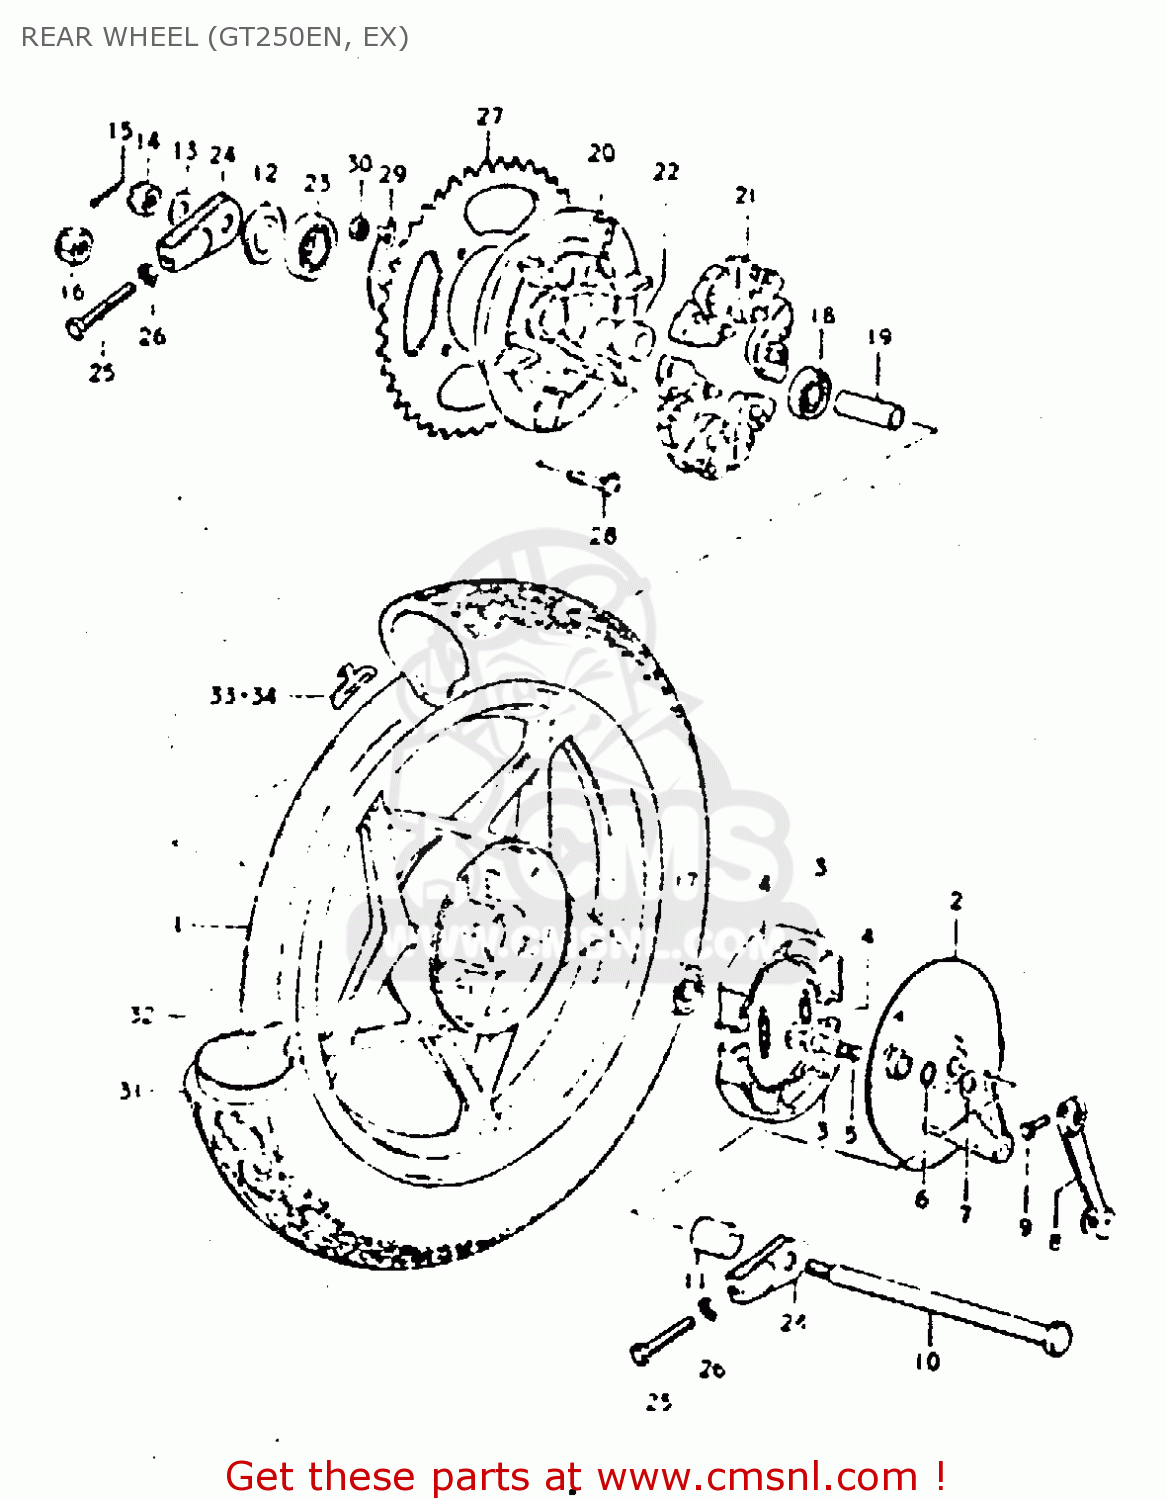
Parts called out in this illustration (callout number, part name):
1	WHEEL, REAR
2	PANEL,REAR HUB
3	SHOE,BRAKE
4	SPRING,BRAKE SHOE
5	CAM,FRONT BRAKE
6	O-RING,BOSS
7	WASHER (15X24X1.6)
8	LEVER,RR BRAKE CAM
9	BOLT
10	AXLE, REAR
11	SPACER
12	SPACER, LH
13	WASHER
14	NUT
15	COTTER PIN
17	BEARING, RH
18	BEARING
19	SPACER(15.3X21.7X58)
20	DRUM,REAR SPROCKET MOUNT
21	ABSORBER,RR HUB SHOCK
22	RETAINER,RR SPROCKET MTG
23	BEARING
24	ADJUSTER,CHAIN,R
25	BOLT
26	NUT
27	SPROCKET,RR
28	BOLT(8X33.5)
29	WASHER,LOCK
30	NUT (8MM)
31	TIRE
32	TUBE ASSEMBLY,WHEEL,INNER
33	BALANCER,WHEEL
34	BALANCER,WHEEL
